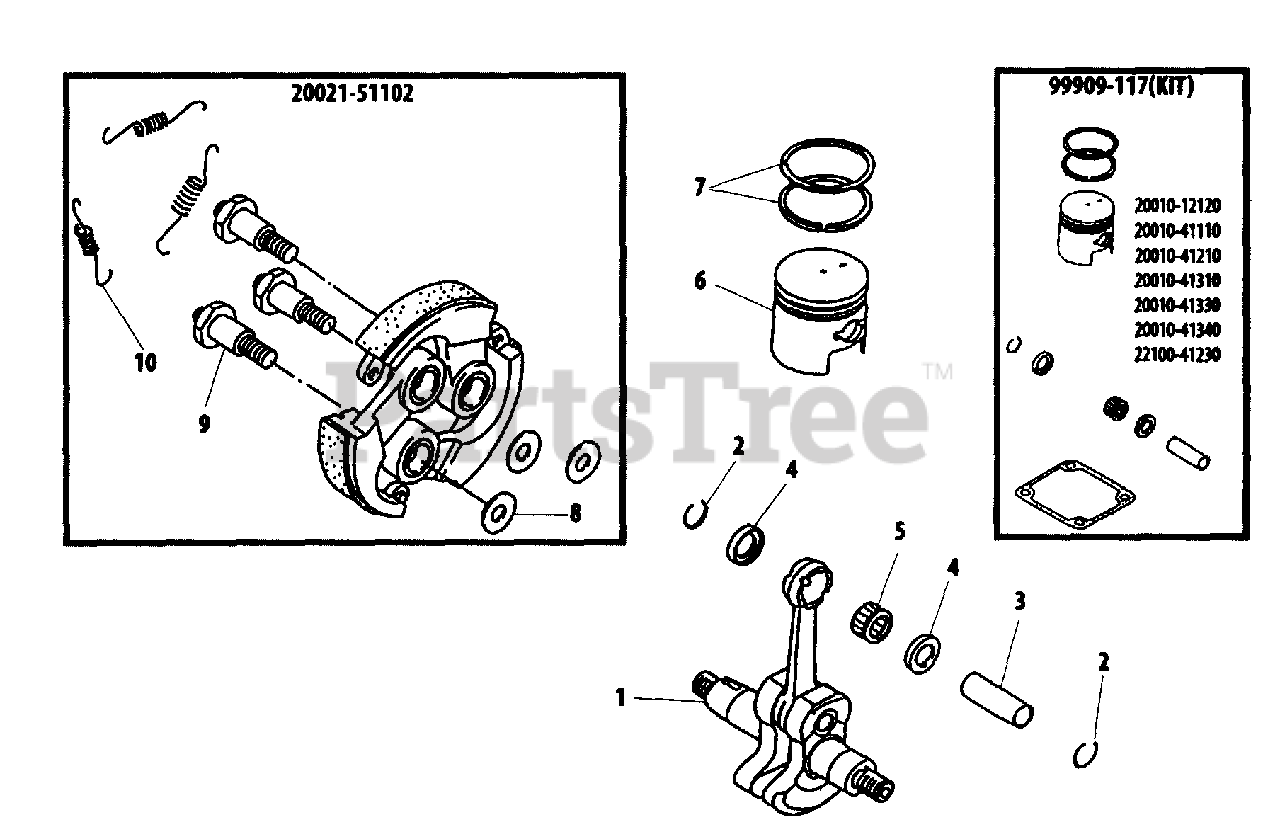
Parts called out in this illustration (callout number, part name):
1	CRANKSHAFT ASSY
2	RING, SNAP
3	PIN, PISTON 10
4	WASHER, THRUST
5	BEARING, NEEDLE 10
6	PISTON
7	RING, PISTON
8	WASHER 6 MM
9	BOLT, CLUTCH
10	SPRING, CLUTCH
20021-51102	CLUTCH ASSY
99909-117	PISTON ASSY
